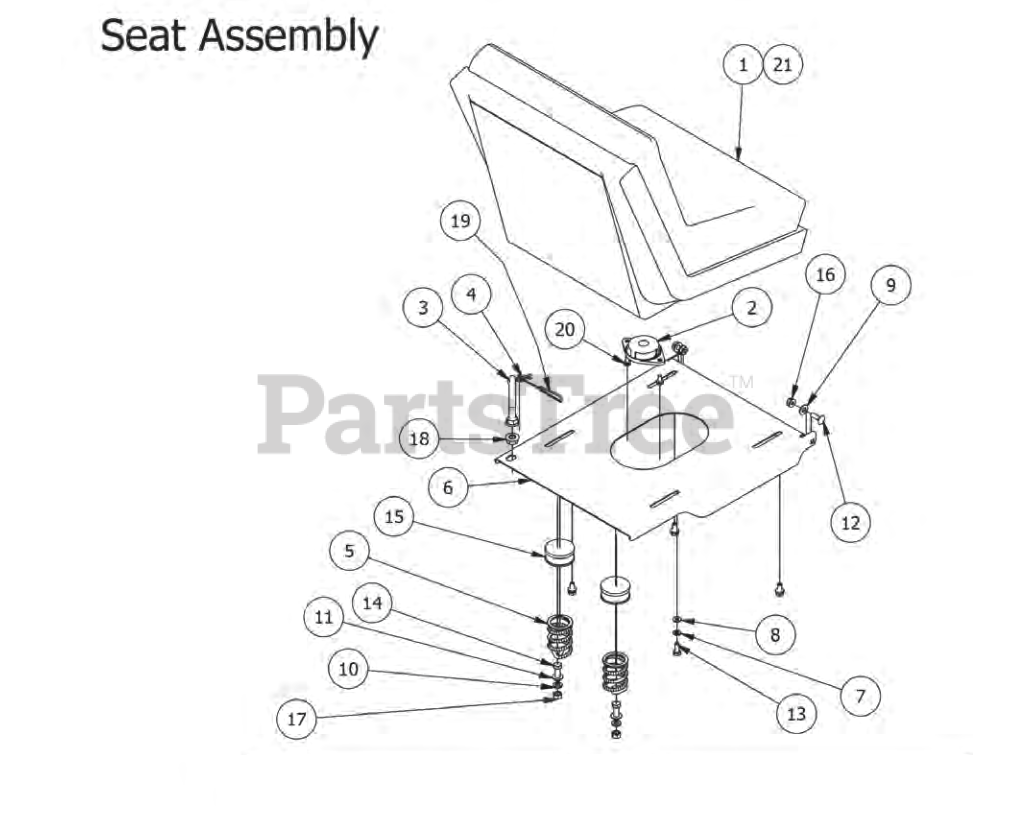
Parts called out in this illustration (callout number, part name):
1	2014 Magnum Seat
2	2014 Seat Safety Switch
3	Seat Bracket Pin
4	Seat latch pin
5	Seat Spring
6	MZ Seat Plate
7	5/16" Lock Washer
8	1/4" Flat Washer
9	.360 ID Plastic Washer
10	3/8" Lock Washer
11	3/8" Flat Washer
12	5/16-18 x 1 Carriage Bolts Zinc
13	5/16" x 3/4" Hex Bolt
14	3/8" x 1 1/4" Hex Bolt
15	Spring Cap Cover
16	5/16-18 Nylon Flange Nut
17	3/8" Hex Nut
18	1/2" Flange Nut
19	seat pin lanyard
20	1/4-20x1/2 HWH Bolt Slot
21	Gray Bucket Seat with No Arms/Sides (Only on 42"MZ)
